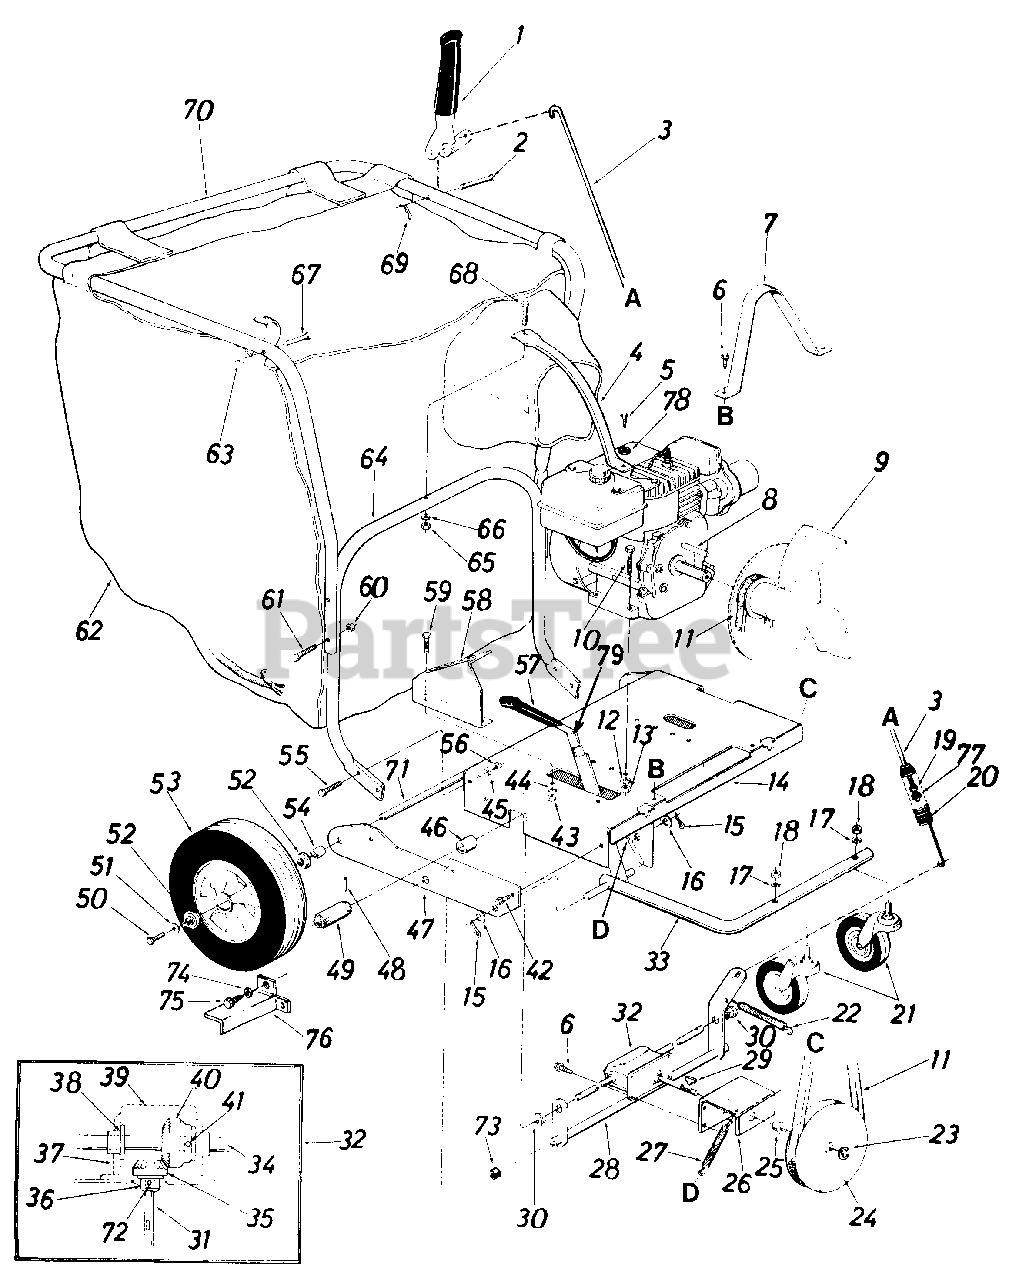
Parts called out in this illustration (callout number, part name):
1	Clutch Grip Ass'y.
2	Clevis Pin .375" Dia. x 1.88" Lg.
3	Clutch Rod 32" Lg.
4	Handle Brace (5 H.P.)
5	Part of Engine
6	Hex Wash. Hd. "AB" 1/4" x .62" Lg.
9	Air Vane Plate Ass'y. w/pulley
10	Hex Bolt 5/16-18 x 1.50" Lg.
11	"V"-Belt 1/2" x 26" Lg.
12	L.-Wash. 5/16" I.D.
13	Hex Nut 5/16-18 Thd.
14	Engine Mounting Frame Ass'y.
15	Cotter Pin 5/32" Dia. x 1.25" Lg.
16	Fl.-Wash. .63" I.D. x 1.25" O.D.
17	L.-Wash. 1/2" I.D.
18	Hex Nut 1/2-13 Thd.
19	Hex Cent. L.-Nut 1/2" I.D.
20	Extension Spring .78" O.D. x 7.50" Lg.
21	Swivel Caster Wheel 5" Dia.
22	Extension Spring .38" O.D. x 3.18" Lg.
23	Snap "E"-Ring .50" Dia. Shaft
24	"V"-Pulley 5/8" x 6.50" O.D.
25	Flange Bearing .502" I.D.
28	Clutch Bracket Ass'y.
29	#2 Woodruff Key 3/32" Dia. x .81" Lg.
30	Hex Flange Bearing Bronze .625" I.D.
31	Pinion Shaft .50" Dia. x 5.0" Lg.
32	Gear Box Ass'y. Comp.
33	Caster Arm Ass'y.
34	Drive Shaft .624" Dia. x 22.75" Lg.
35	Bevel Gear .50" I.D. x 14 Teeth
36	Flange Bearing .503" I.D.
37	Gear Box
38	Flange Bearing .630" I.D.
39	Gear Box Cover
40	Bevel Gear .62" I.D. x 28 Teeth
41	Spring Pin Spiral 3/16" Dia. x 1.25" Lg.
42	Hex Wash. Hd. "AB" Tap Scr. 5/16" x .75" Lg.
43	Hex Nut 5/16-18 Thd.
44	L.-Wash. 5/16" I.D.
45	L.-Wash. 5/16" I.D.
46	Space .63 I.D. x .88" O.D. x .56 Lg.
49	Drive Pinion
50	Hex Locking Bolt 5/16-24 x .62" Lg.
51	Fl.-Wash. .34" I.D. x .87" O.D.
52	Ball Bearings
53	Wheel Ass'y. - Comp. 12" x 3"
54	Spacer .63" I.D. x 1.00" O.D. x .94" Lg.
55	Hex Bolt 5/16-18 x .75" Lg.
56	Hex Nut 5/16-18 Thd.
57	Flat Grip Vinyl
58	Index Plate
59	Hex Bolt 5/16-18 x .75" Lg.
60	Hex Cent. L.-Nut 1/4-20 Thd.
61	Hex Bolt 1/4-20 x 1.75" Lg.
62	Vacuum Bag - Felt
63	Push Speed Nut for .25" Dia. Stud
64	Lower Handle
65	Hex Nut 1/4-20 Thd.
66	L.-Wash. 1/4" I.D.
67	Stud Pin .250" Dia. x 1.75" Lg.
68	Hex Bolt 1/4-20 x 1.75" Lg.
69	Internal Cotter Pin 3/8" Dia.
70	Upper Handle
71	Rear Axle .624" Dia. x 24.37" Lg.
72	Spring Roll Pin 5/32" Dia. x 1.12
73	Spacer.82" I.D. x 1.00" O.D. x .305" Lg.
74	L.-Wash. .265" I.D.
75	Hex Self-Tap Scr. 1/4" x 3/8" Lg.
78	Belleville Washer
79	Height Adj. Handle
14530-0499	PLATE-SIDE-RH - CUB BEIGE (0499)
14530-0637	PLATE-SIDE-RH - POWDER BLACK (0637)
14530-0662	PLATE-SIDE (RH) - OYSTER GRAY (0662)
